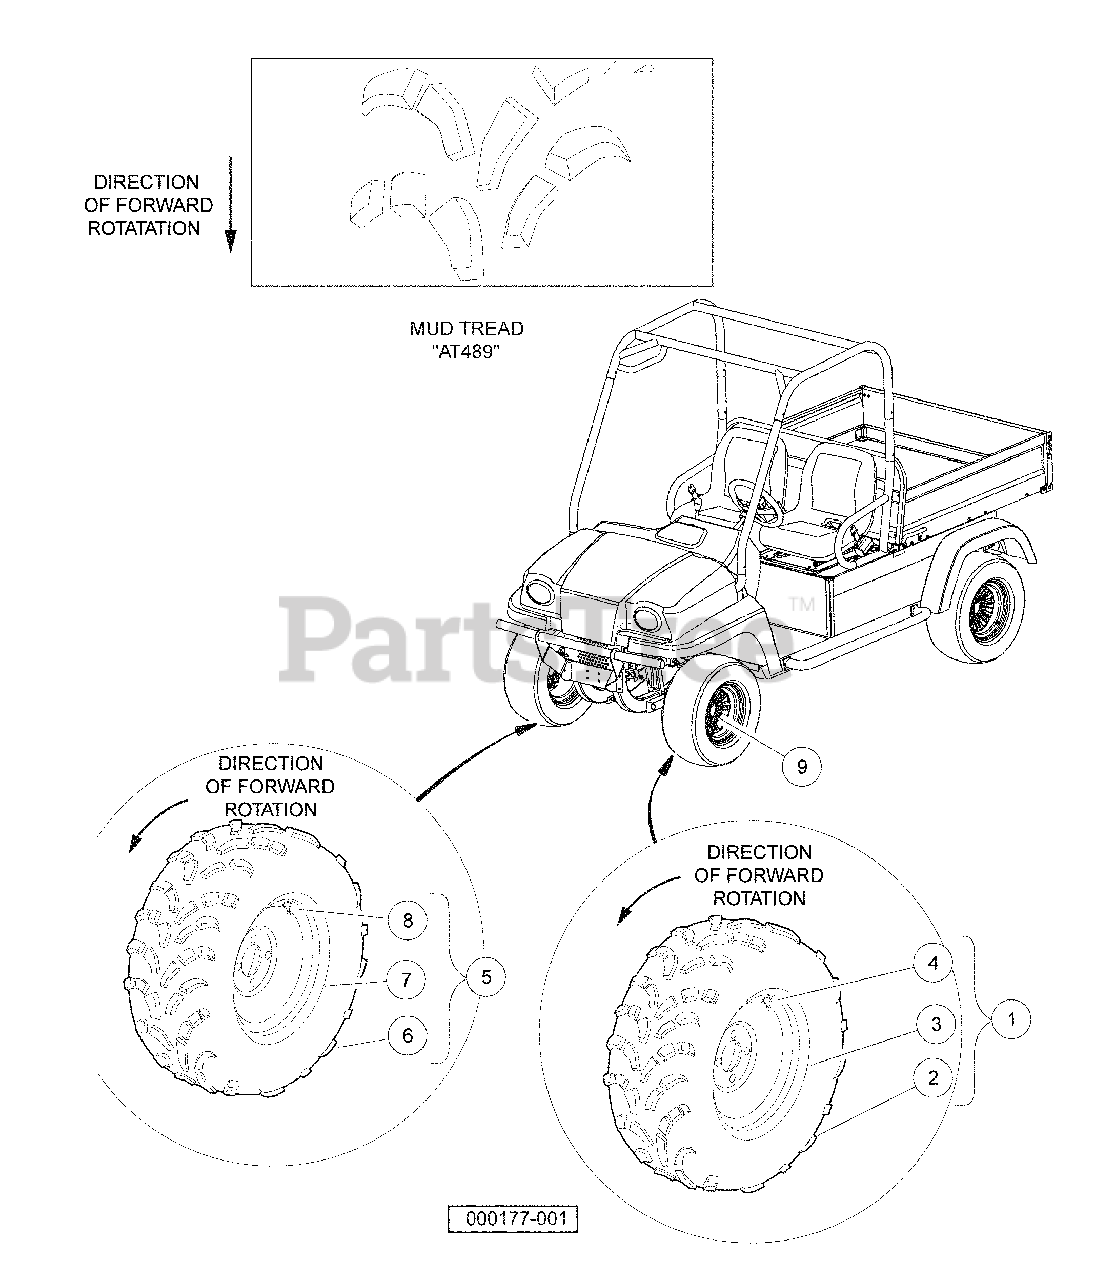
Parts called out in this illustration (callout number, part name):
1	Gray Tire Assembly, AT489 LH
2	Tire, AT489
3	Wheel, Indus Spider, Gray
4	Valve Stem
5	Gray Tire Assembly, AT489 RH
6	Tire, AT489
7	Wheel, Indus Spider, Gray
8	Valve Stem
9	Nut, Lug, 1/2-20 SAE J2283
